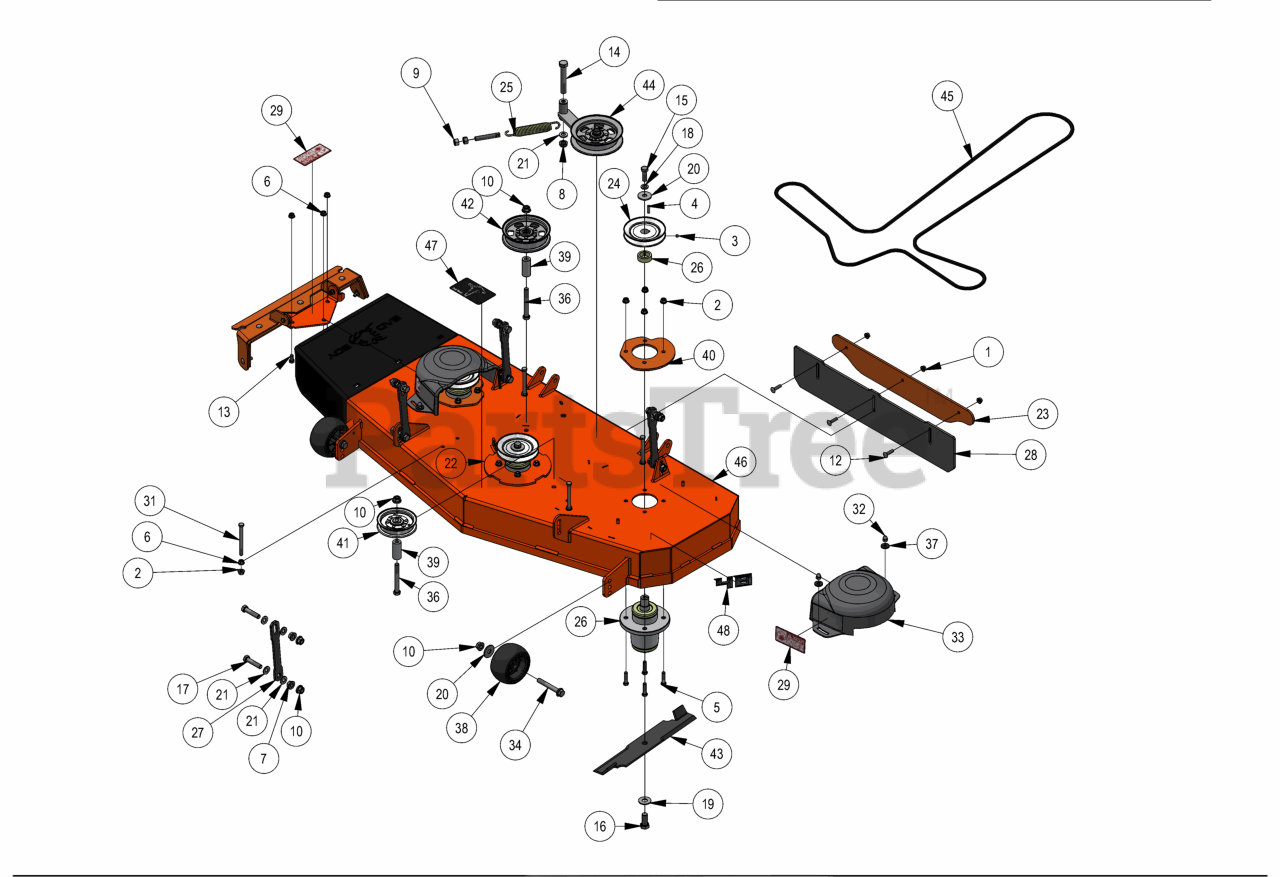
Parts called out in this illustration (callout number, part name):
1	5/16-18 NYLON INSERT FLANGE LOCKNUT ZINC
2	3/8-16 NYLON INSERT FLANGE LOCKNUT (GR.F) ZINC
3	5/16-24 X 1/4 SOCKET SET SCREW (CUP PT) PLAIN
4	1/4 X 1 SQ MACHINERY KEY 1018 STL PLN
5	3/8-16 X 1-1/2 HEX CAP SCREW (GR.5) ZINC
6	3/8-16 HEX SERRATED FLANGE NUT HARD/ZINC
7	1/2-13 HEX SERRATED FLANGE NUT HARD/ZINC
8	5/8-11 NYLON INSERT JAM LOCKNUT ZINC
9	1/2-13 HEX NUT ZINC
10	1/2-13 NYLON INSERT FLANGE LOCKNUT ZINC
11	All Thread
12	5/16-18 X 1-1/4 CARRIAGE BOLT ZINC
13	3/8-16 X 3/4 HEX CAP SCREW (GR.5) ZINC
14	5/8-11 X 4 HEX CAP SCREW (GR.8) ZINC YELLOW
15	1/2"-20 x 1 1/2 - Grade 5 Fine Thread Bolt
16	5/8-18 X 1-1/2 HEX CAP SCREW (GR.8) ZINC YELLOW
17	1/2-13 X 2-1/4 HEX CAP SCREW (GR.5) ZINC
18	1/2 SPLIT LOCKWASHER (GR.8) ZINC/YELLOW
19	5/8 USS FLAT WASHER (1-3/4" OD) GR.8 ZINC YELLOW
20	1/2 BELLEVILLE WASHER (1-5/8 OD X .140 THK) ZINC
21	.505 ID X 1.000 OD X .125 THICK FLAT WASHER NYLON
22	Deck Spindle Support Plate
23	Striping Kit Plate
24	5" Spindle Deck Pulley
25	Deck Idler Spring
26	OUTLAW SPINDLE ASSEMBLY
27	23WB Deck Hanger
28	2023 MZ Stripping Kit Rubber
29	Danger Decal-Spindle/Discharge
30	ZT Chute Assembly
31	3/8-16 X 4-1/4 HEX CAP SCREW (GR.5) ZINC
32	5/16-18 ACORN NUT HIGH-CROWN ZC
33	Pulley Cover
34	1/2-13 X 90MM HEX FLANGE BOLT W/SHOULDER (GR.8) ZINC
35	1/2-13 NYLON INSERT JAM LOCKNUT ZINC
36	1/2-13 X 4 HEX CAP SCREW (GR.8) ZINC YELLOW
37	.360 ID X .983 OD X .120 THICK FLAT WASHER NYLON BLACK
38	Deck Wheel
39	2019 Revolt Stationary Idle Spacer
40	42&48 Deck Spindle Support Plate
41	4 3/4" Idler Pulley
42	5-3/4 Idler Pulley
43	48" ZT/Mav/Compact Outlaw Blade with Fusion
44	2019 Revolt Deck Idler Assembly
45	42 inch Deck Belt- B120
46	23WB 48in Deck
47	2017 MZ Magnum 48"/42" Deck Route Decal
48	48" Deck Decal
